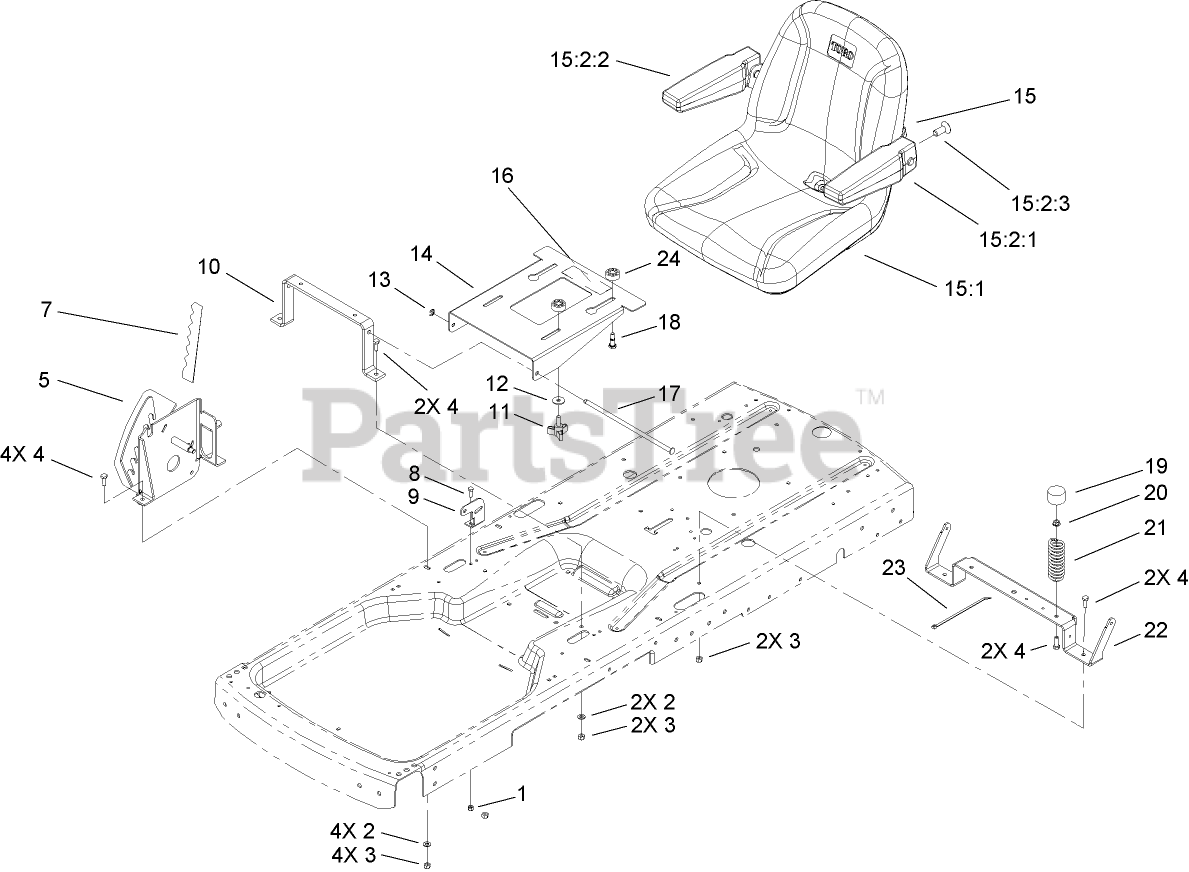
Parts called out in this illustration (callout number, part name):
1	NUT-LOCK, NI
2	WASHER-PLAIN
3	NUT-LOCK, NI
4	SCREW-HH
5	RH PLATE ASM
7	DECAL-HOC
8	SCREW-HH
9	BRACKET-BELLCRANK
10	BRACE-SEAT, FRONT
12	WASHER-PIVOT
13	E-RING
14	BRACKET-SEAT
15	SEAT (WITH ARM RESTS)
15:1	SEAT
15:2:3	SCREW-HSBH
16	DECAL-SERVICES
17	PIN-PIVOT
18	SCREW-SHOULDER
19	CAP-PROTECTOR
20	NUT-HF
21	SPRING-COMPRESSION
22	BRACE-SEAT, REAR
23	TIE-CABLE
24	SPACER-NYLON
